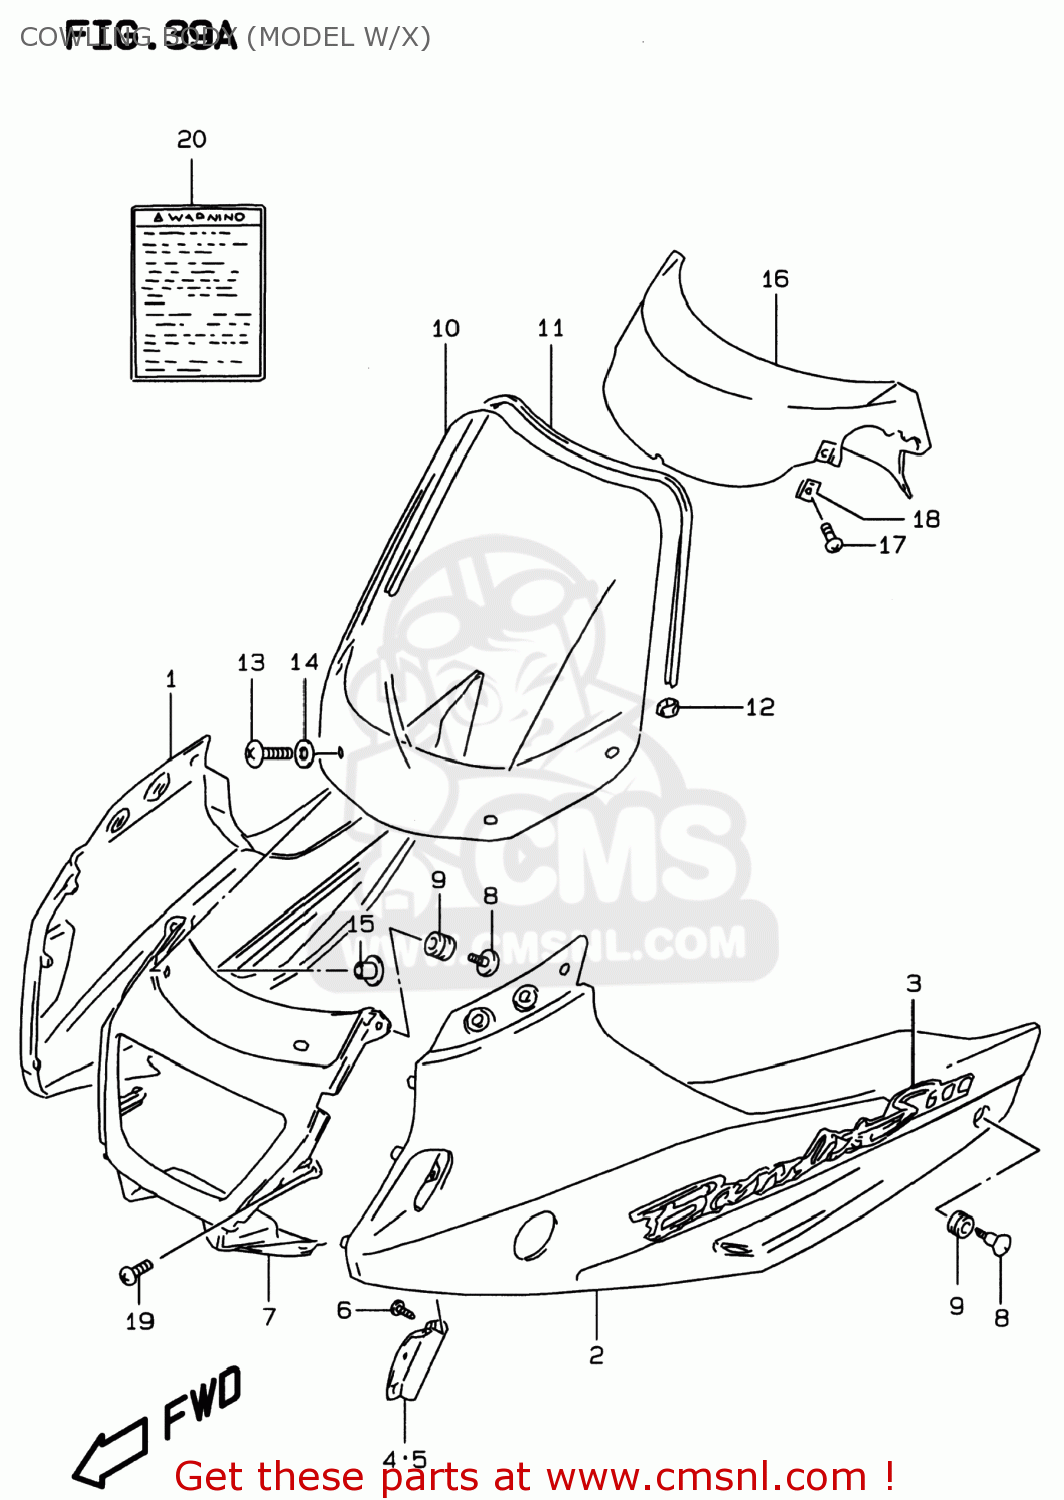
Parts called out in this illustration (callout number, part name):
1	COWLING ASSY,SIDE,R
2	COWLING ASSY,SIDE,L
3	EMBLEM,COWLING SIDE
4	COVER,COWLING INNER,R
5	COVER,COWLING INNER,L
6	SCREW 5X10
7	COWLING ASSY,CTR
8	SCREW(6X20)
9	CUSHION
10	WINDSCREEN SET
11	MOLDING WINDSCREEN
12	CLIP,WINDSCREEN MOLDING
13	SCREW(5X14)
14	WASHER
15	NUT
16	PANEL,INNER
17	SCREW
18	NUT
19	SCREW
20	LABEL (WARNING SCREEN)
